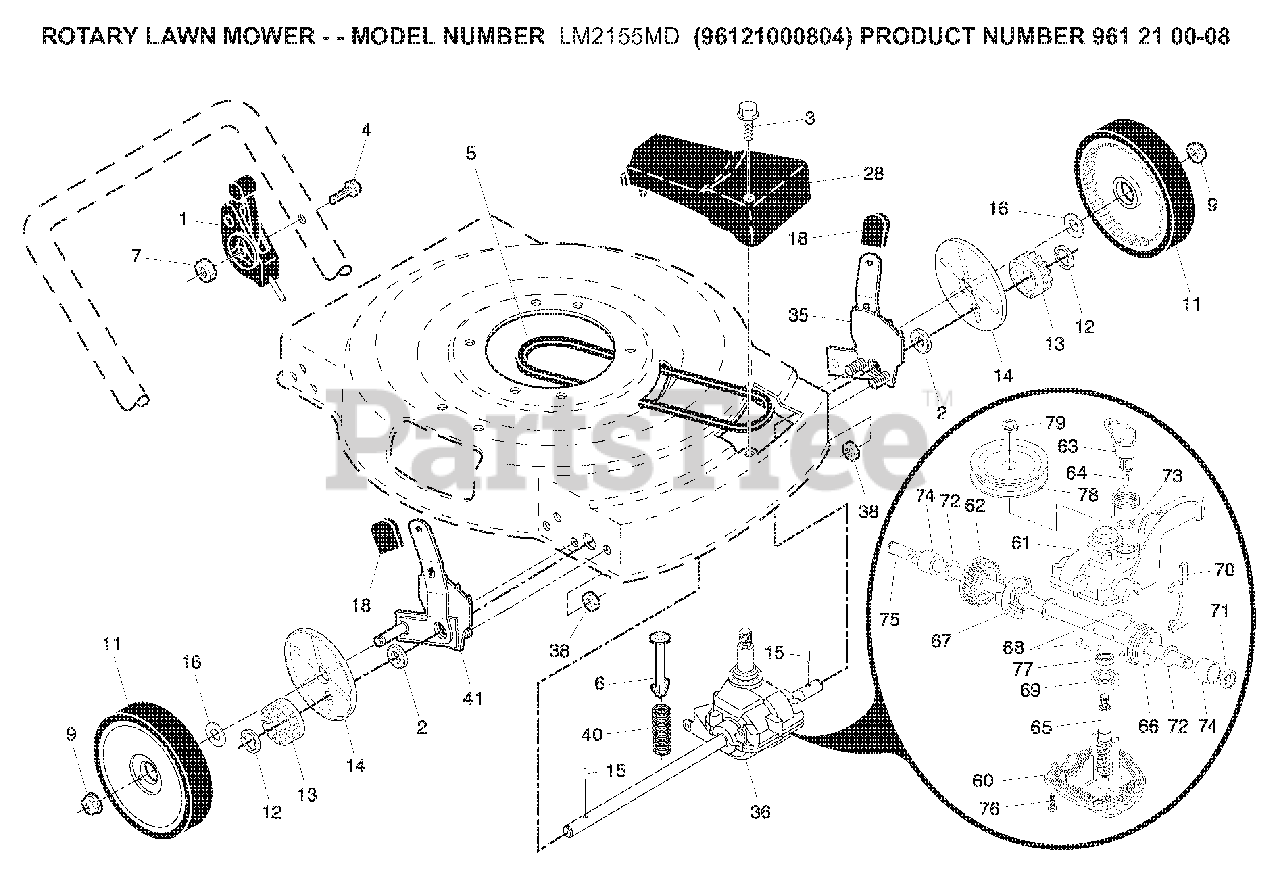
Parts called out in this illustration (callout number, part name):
1	DRIVE CONTROL 59.8 FWGD
2	BEARING ASM
5	BELT THERM .32
6	SPRING RETAINER
7	NUT.HEX.FLANGE.1/4
9	NUT.HEX.FLANGE.3/8-16.LOCKNUT
12	E-RING 7/16 RE
13	PINION.14.TEETH.FGD
14	COVER.DUST.WHEEL
15	PAWL, DRIVE
16	WASHER FLUT
18	SELECTOR KNOB
35	WHEEL ADJ KIT LH
38	LOCKNUT
40	SPRING.EXTENSION
41	WHEEL ADJ KIT RH
60	LOWER CASE
61	UPPER CASE
62	GEAR.27.TEETH.WALK.MOWER
63	LEVER, CLUTCH
64	SPRING, RETURN
65	SHAFT.INPUT.WORM.GEAR(13155)
66	DOG, MOVABLE
67	DOG, FIXED
68	WIRE, FORMED
70	FORK, SHIFT
71	SEAL.OUTPUT.SHAFT
73	SEAL, CASE
75	SHAFT OUTPUT
77	SEAL INPUT SHAFT
78	FLASK.PULLEY
79	NUT.WITH.FLAT.BROKE
